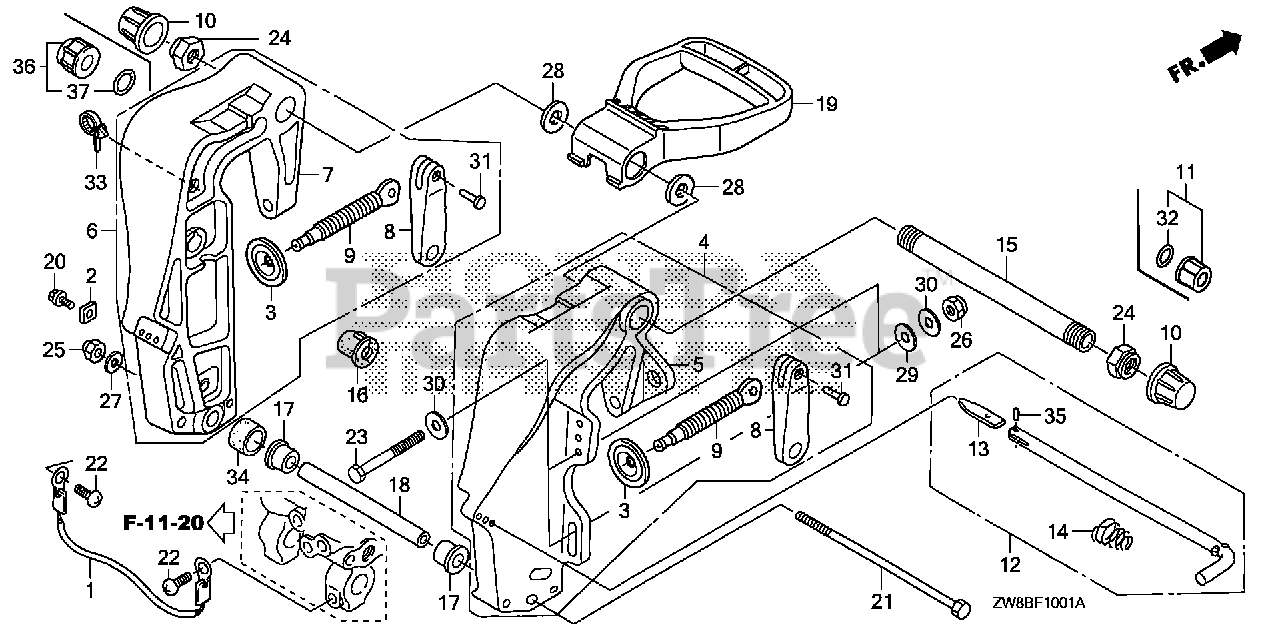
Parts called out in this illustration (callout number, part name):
1	WIRE, LEAD (1.5X170MM)
2	METAL, ANODE
5	BRACKET, R. STERN *NH282MU* (OYSTER SILVER METALLIC-U)
7	BRACKET, L. STERN *NH282MU* (OYSTER SILVER METALLIC-U)
10	CAP, TILTING BOLT
12	ROD, ADJUSTING
13	STOPPER, ROD
14	SPRING, ADJUSTING ROD
15	SHAFT, TILTING
16	BUSH, MOTOR CODE
17	BUSH, CYLINDER (LOWER)
18	COLLAR, CYLINDER (LOWER)
19	HANDLE, CARRYING REMOTE
20	BOLT, FLANGE (6X12) Use from Frame SN 1005249.
21	BOLT, HEX. (8X203)
22	SCREW, PAN (6X8)
23	BOLT, HEX. (10X100)
24	NUT, SELF-LOCK (7/8-14UNF)
25	NUT, SELF-LOCK (8MM)
26	NUT, SELF-LOCK (10MM)
27	WASHER, PLAIN (8MM) Use up to Frame SN 4800712.
28	WASHER, WAVE (22MM)
29	WASHER, PLAIN (10MM)
30	WASHER, PLAIN (10MM)
32	O-RING (15.54X2.26)
33	CLIP, HARNESS BAND (145MM) (BLACK)
34	COLLAR, DISTANCE
35	PIN, SPRING (2.5X8)
36	CAP ASSY.
37	O-RING (15.54X2.26)
